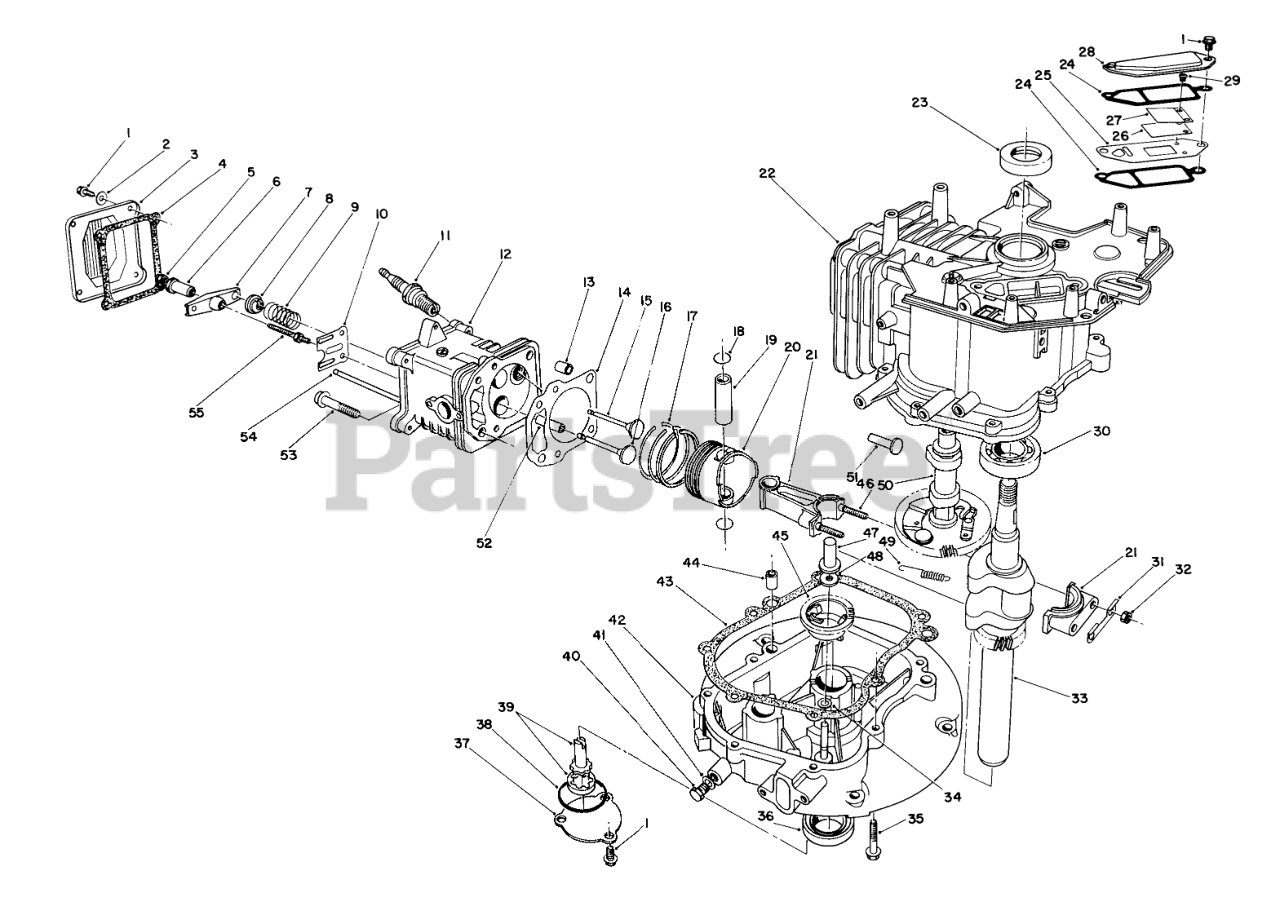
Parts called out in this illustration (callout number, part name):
2	WASHER
3	COVER
4	GASKET
6	PIVOT
8	RETAINER
9	SPRING
10	GUIDE
11	SPARK PLUG
12	Head-Cylinder (Incl. Ref. #52)
14	GASKET
15	VALVE-EXHAUST
16	VALVE-INTAKE
17	RING SET
18	CIRCLIP
20	PISTON
21	Connecting Rod Assembly (Incl . Ref . #31, 32 & 46)
22	Block-Engine (Incl. Ref. #23 & 30)
24	GASKET
25	Plate-Breather
26	Valve-Reed
27	Retainer-Reed Valve
28	COVER
29	Screw-Reed Valve
30	BEARING
31	Plate-Lock
33	CRANKSHAFT
34	WASHER
37	COVER
38	O-RING
39	OIL PUMP
40	OIL DRAIN PLUG
41	GASKET
42	Crankcase
43	GASKET
45	GOVERNOR FLYWEIGHT ASM
47	PLUNGER
48	WASHER
49	SPRING
50	Camshaft Assembly (Incl. Ref. #49)
51	TAPPET
52	GUIDE
